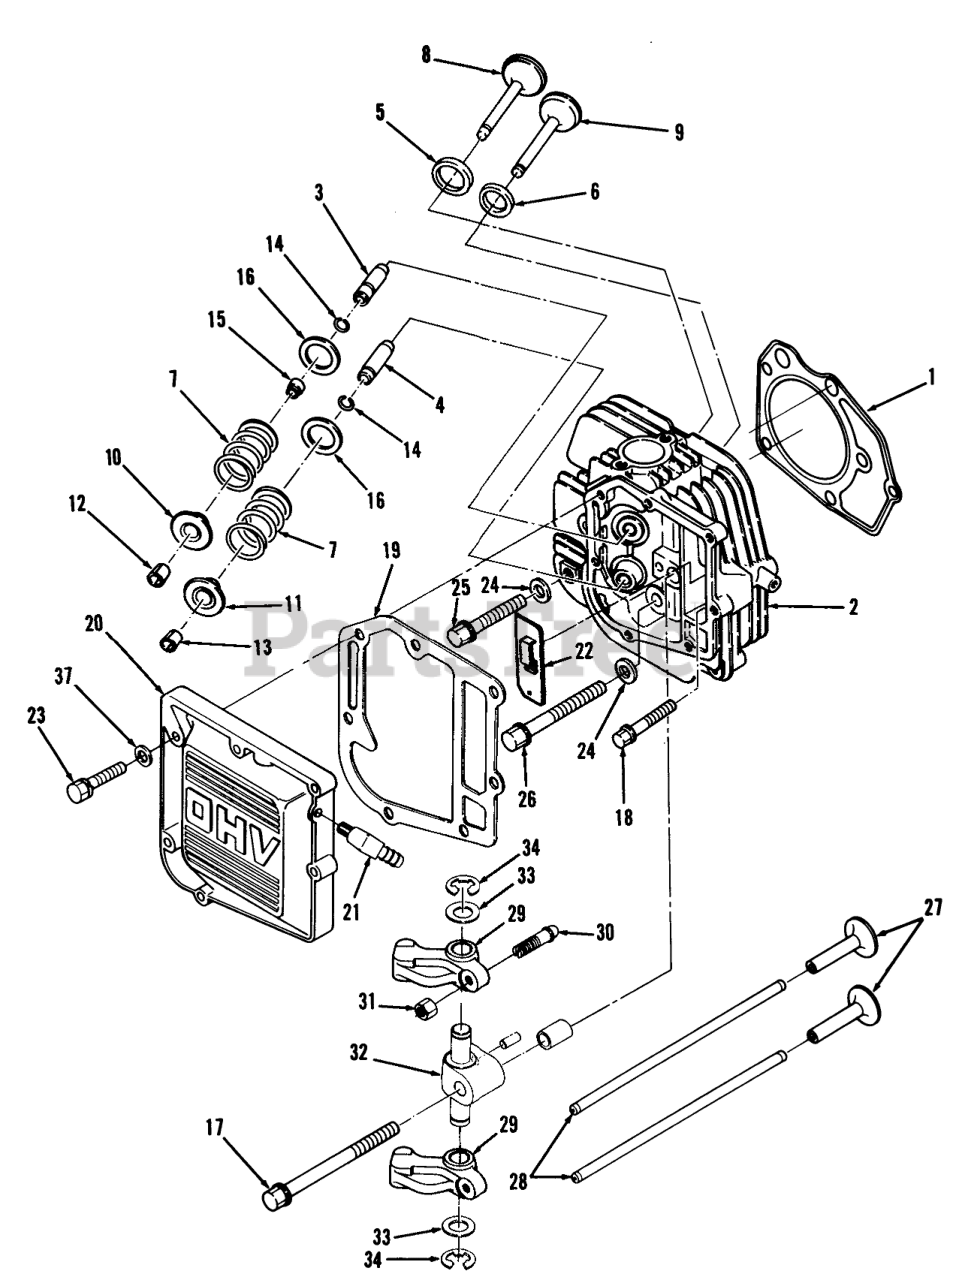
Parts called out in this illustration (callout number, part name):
1	GSKT-CYL HEAD
2	Cylinder Head Assembly (Incl. Ref. #3-16)
3	GUIDE-INTAKE VALVE
4	GUIDE-EXH VALVE
5	Seat-Intake Valve
6	Seat-Exhaust Valve
7	SPRING-VALVE
8	VALVE-INTAKE MKD IN
9	VALVE-EXHAUST MKD EX
10	RETAINER-VLV SPG IN
11	RETAINER-VLV SPG EX
12	Lock-Intake
13	LOCK-VALVE EXHAUST
14	RING-VALVE GUIDE
15	Seal-Intake
16	WASHER-VALVE SPRING
17	BLT-CYL HD M10X125MM
18	BLT-CYL HD M8X50MM
19	Seal
20	Cover-Valve
21	ELBOW-90 DEGREES
22	BREATHER
23	SCRW-CP SH M6X25MM
24	WASHER-FLAT M10
25	BLT-CYL HD M10X66MM
26	BLT-CYL HD M10X86MM
27	TAPPET
28	ROD-PUSH
29	Rocker Arm Assembly (Incl. Ref. #30 & 31)
30	SCRW-LASH ADJUSTING
31	NUT-LASH ADJUSTING
32	SHAFT-ROCKER ARM
33	Rocker Arm Washer
34	CLIP-RETAINER
35	PIN-DOWEL
36	PIN-DOWEL HOLLOW
37	WASHER-FLAT
